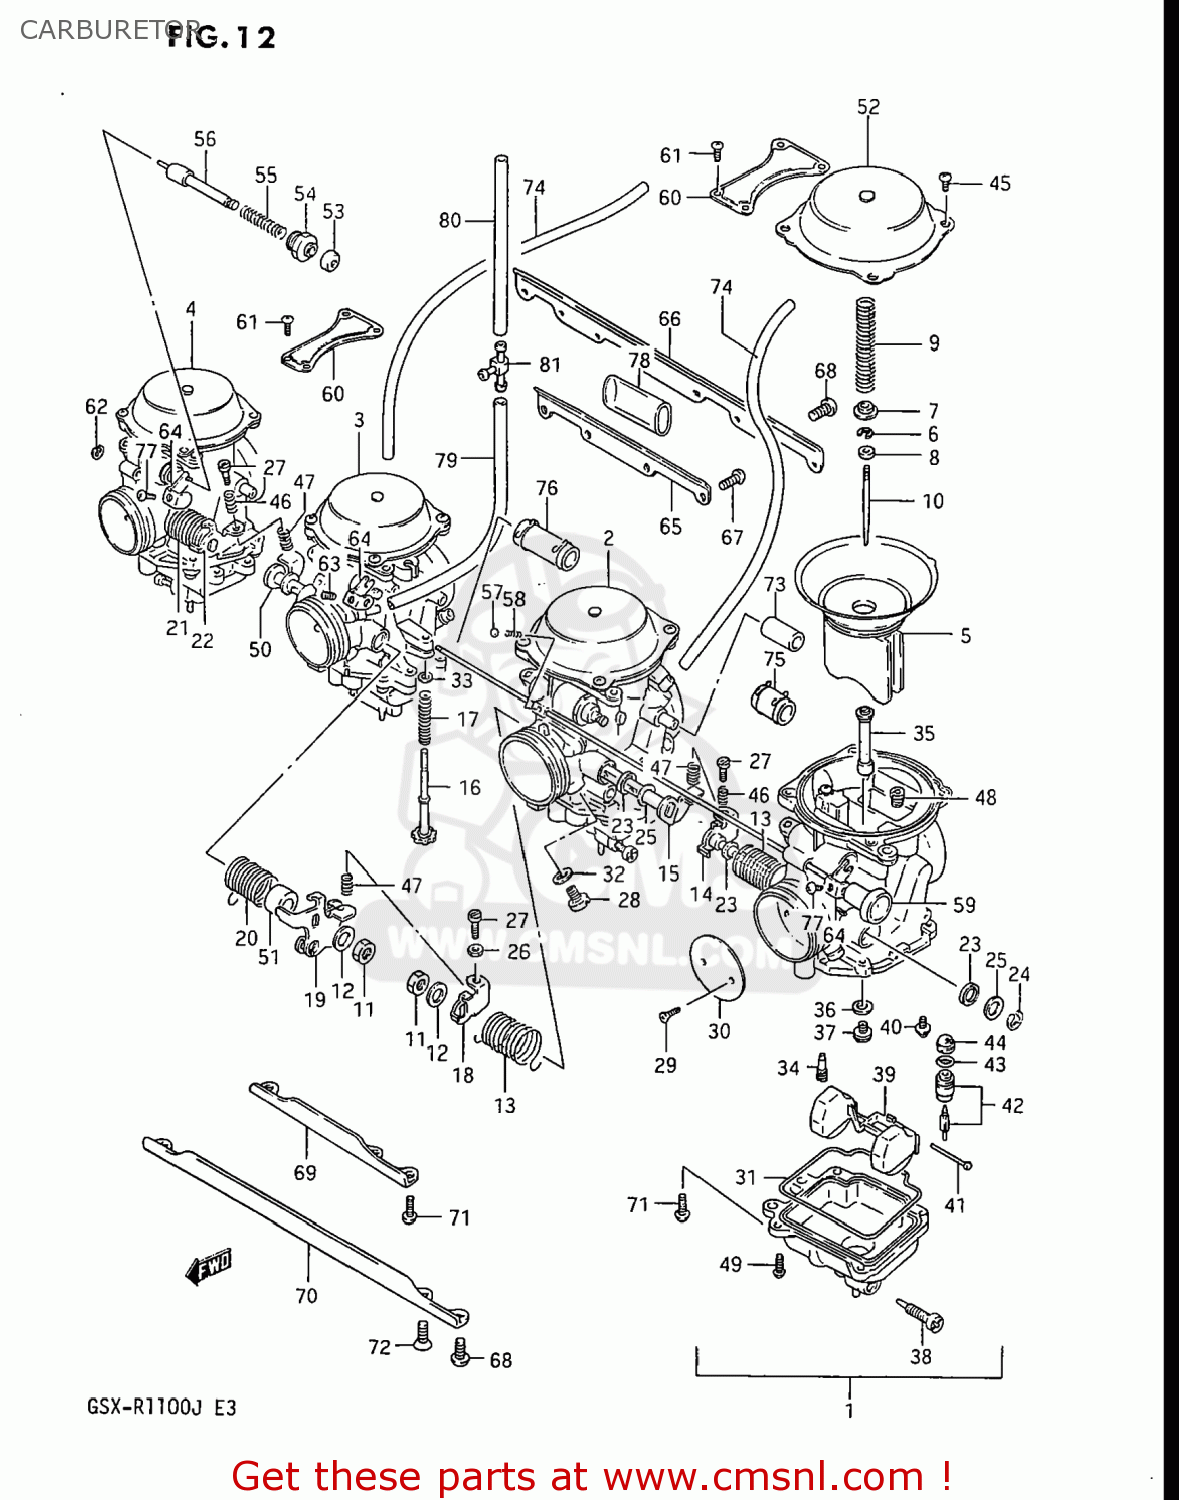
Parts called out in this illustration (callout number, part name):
1	CARBURETOR ASSEMBLY
2	CARBURETOR ASSEMBLY
3	CARBURETOR ASSEMBLY
4	CARBURETOR ASSEMBLY
5	DIAPHRAGM ASSY
6	CAP,LEVER
7	RING
8	RING
9	SPRING
10	NEEDLE,JET
11	NUT
12	WASHER
13	SPRING
14	SHAFT ASSEMBLY
15	SHAFT ASSEMBLY
16	ADJUSTER
17	SPRING
18	LEVER
19	LEVER ASSEMBLY
20	SPRING
21	SPRING
22	SHAFT ASSEMBLY
23	SEAL
24	E RING
25	GASKET,THROTTLE SHAFT (NAS)
26	NUT,THROTTLE ROD
27	SCREW
28	SCREW
29	SCREW
30	VALVE,THROTTLE (125)
31	O RING,FLOAT CHAMBER
32	WASHER
33	WASHER
34	JET,PILOT(32.5)
35	JET,NEEDLE (P-2)
36	WASHER,NEEDLE NOZZLE
37	JET,MAIN(130)
38	SCREW
39	FLOAT
40	SCREW
41	PIN,FLOAT
42	VALVE ASSY,NEEDLE
43	O RING
44	FILTER
45	SCREW
46	SPRING
47	SPRING,THROTTLE SCREW
48	JET,AIR
49	SCREW
50	SHAFT ASSEMBLY
51	RING
52	COVER,DIAPHRAGM
53	CAP,STARTER VALVE
54	GUIDE SCREW,PLUNGER
55	SPRING
56	PLUNGER ASSY
57	BALL,CARBURETOR
58	SPRING
59	SHAFT ASSEMBLY
60	PLATE
61	SCREW
62	E-RING
63	SCREW
64	LEVER
65	PLATE
66	PLATE
67	SCREW
68	SCREW
69	PLATE
70	PLATE
71	SCREW
72	SCREW
73	HOSE,CARBURETOR
74	HOSE
75	HOSE SET (3X5X18)
76	HOSE ASSY
77	SCREW
78	HOSE
79	HOSE
80	HOSE
81	NIPPLE
